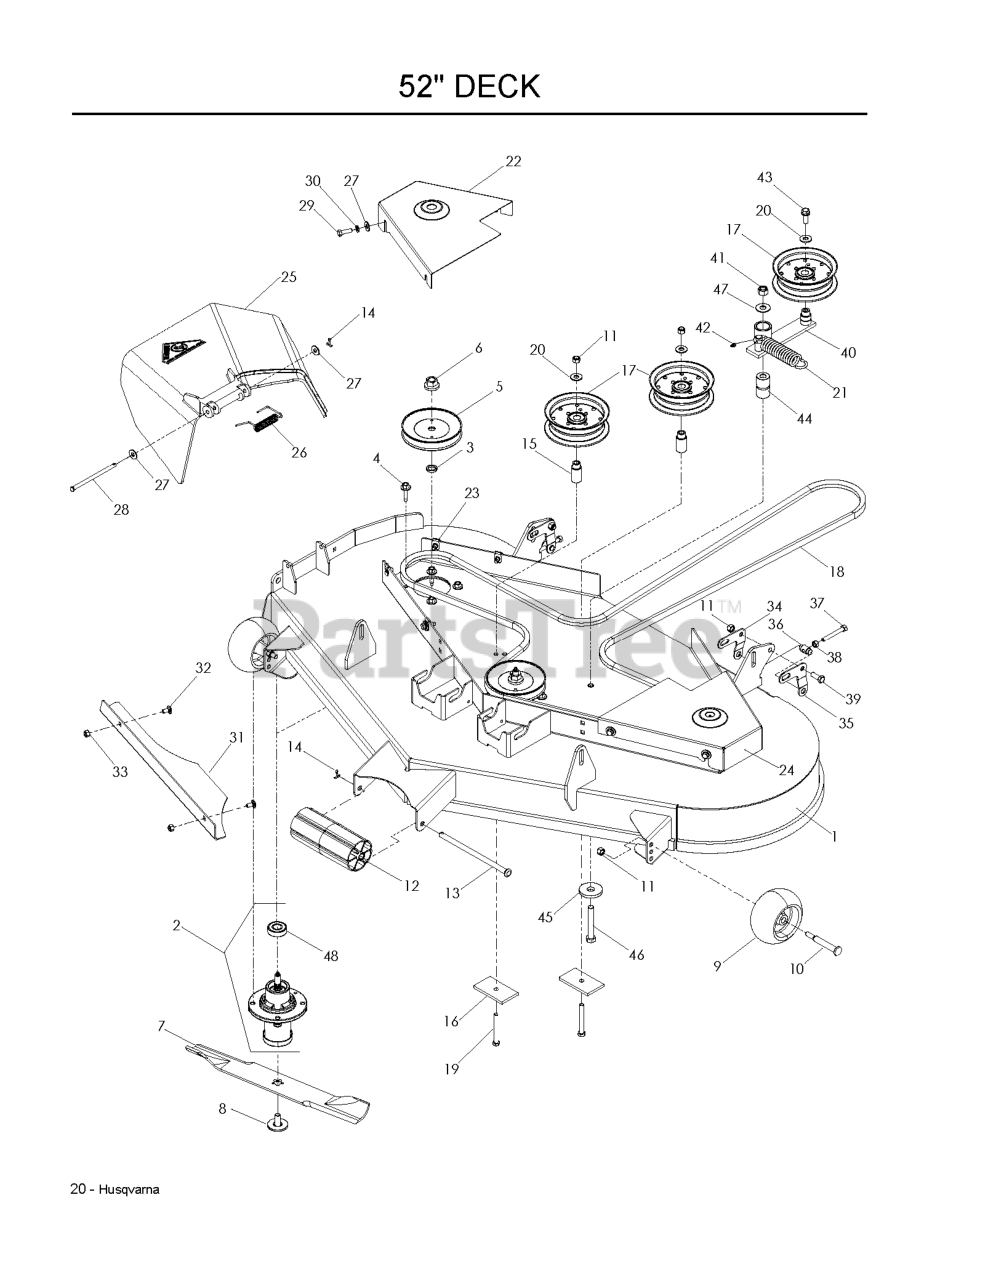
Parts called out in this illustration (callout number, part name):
1	DECK.FAB.W/DECALS.52".MZ.ORANG
2	MANDREL.DECK.ASSEMBLY
3	WASHER-SPACER
4	WASHER HEAD SCREW
5	PULLEY
6	LOCKNUT - 9/16
7	BLADE, 18"
8	BLADE BOLT ASSY-7/16" TB REPL
9	GAUGE WHEEL
10	SHOULDER BOLT 1/2X2-5/8 ZD SPE
11	NUT 3/8-16 NYLOC
12	NOSE ROLLER 48"
13	NOSE ROLLER ROD
14	RP_COTTER PIN 1/8 X 3/4
15	IDLER BUSHING
16	SUPPORT PLATE
17	PULLEY, IDLER
18	BELT.DECK.52".54"
19	HCS 3/8C X 3
20	WASHER 3/8 FLAT
22	BELT SHIELD, RIGHT 52, ORG
23	U-CLIP 5/16-18 NUT RETAINER
24	BELT SHIELD, LEFT 52, ORG
25	DISCHARGE CHUTE 52"
26	SPRING - TORSION
27	WASHER 5/16 FLAT
28	PIN-CLEVIS 5/16 DIA X 5.19 ZD
29	HCS 5/16C X 1
30	WASHER.LOCK.HVY.HLCL.SPR.5/16
31	CONFINEMENT PLATE, 52"
32	CARRIAGE BOLT 5/16C X 5/8"
33	NUT 5/16 NYLOC
34	PITCH, ADJUST, RT
35	PITCH, ADJUST, LT
36	TRUNION, PITCH
37	HCS 5/16-18 X 2 1/2 TPBLT
38	NUT 5/16C HEX
39	HCS 3/8-16X1.GRD.5.ZD
41	NUT 1/2-13 HEX NYLOC ZD
42	ZERK
43	4CS 3/8C X 1 SERRATED HEAD
44	PIVOT BUSHING
45	WASHER, SUPPORT
46	HCS 1/2C X 3 1/4
47	WASHER 1/2 FLAT
48	BEARING, BALL
